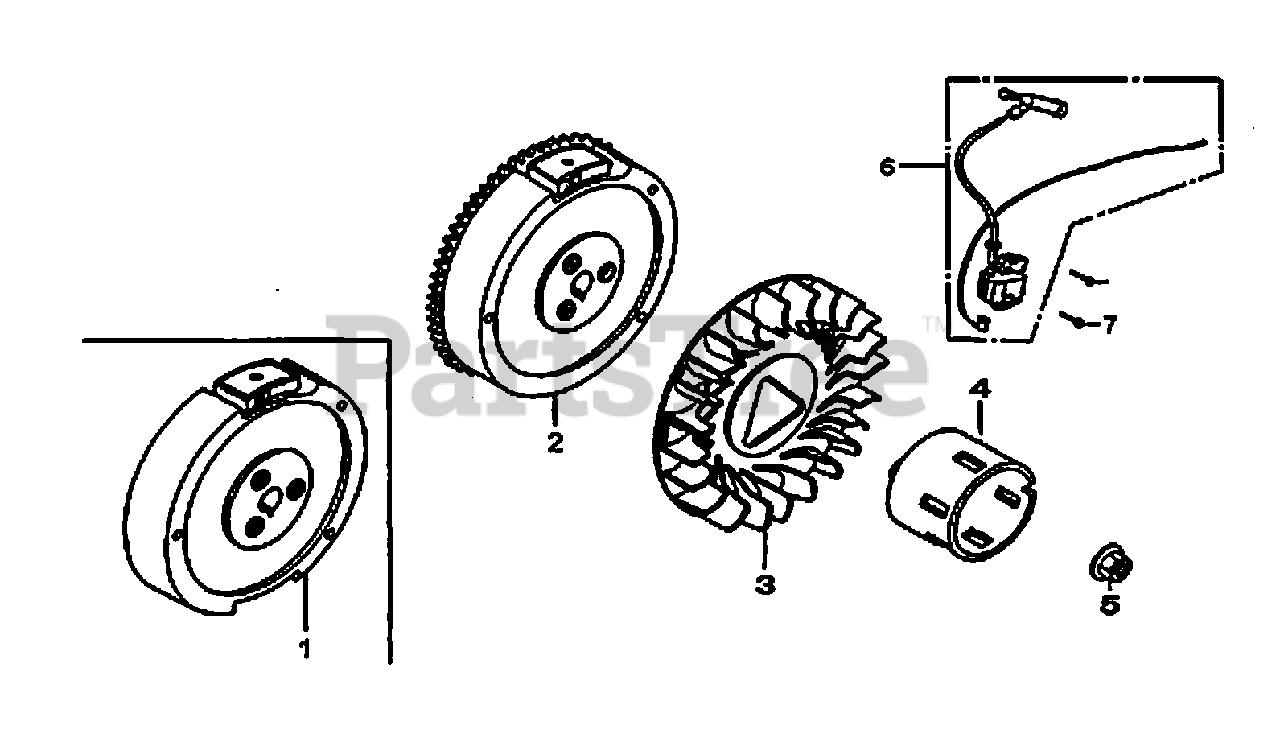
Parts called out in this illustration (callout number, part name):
1	FLYWHEEL COMP.
3	FAN COOLING
4	PULLEY' STARTER
5	NUT SPECIAL' M16
6	COIL ASSY.' IGNITION
7	BOLT' FLANGE' M6X25
